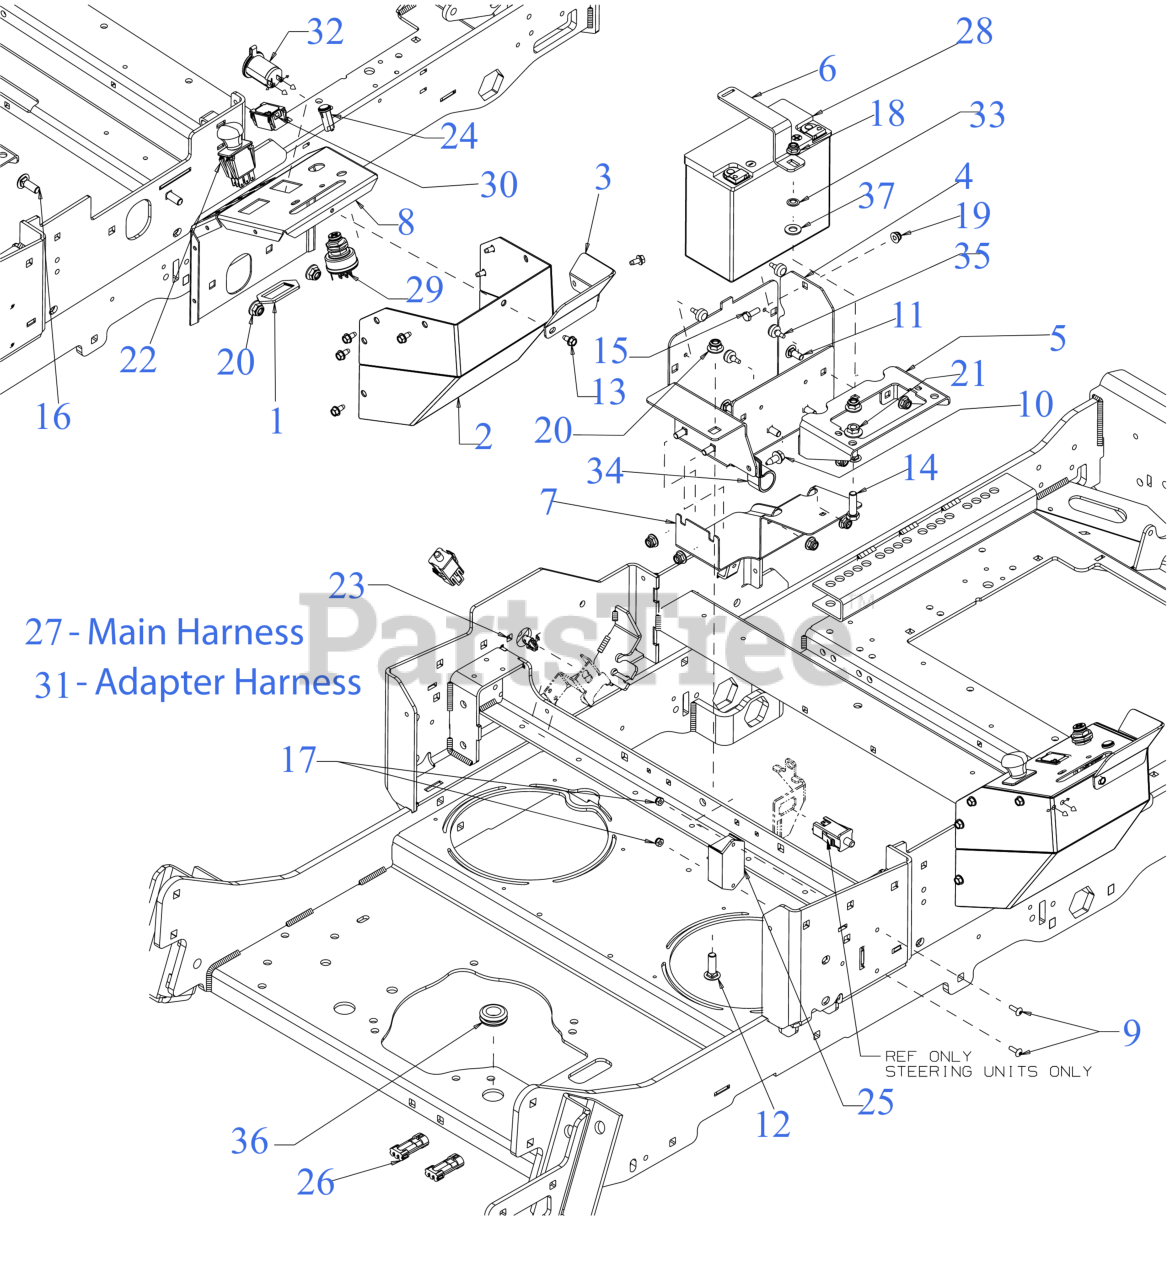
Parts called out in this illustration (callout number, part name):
1	BRACKET-PTO SWITCH
4	BATTERY MOUNT BRACKET
5	FUSE/RELAY MOUNT BRACKET
6	BATTERY SUPPORT BRACKET
7	HOSE/BELT COVER
8	CONTROL POD (RH)
9	SCREW #10-24 x .62
10	SCREW 5/16-18 x .750
11	CARRIAGE BOLT 5/16-18 x .75
12	CARRIAGE BOLT 3/8-16 X1.25 GR5
13	SCREW 1/4-20 X.500
14	SCREW 3/8-16 x 1.25 GR5
15	SCREW 1/4-20X.75 GR5
16	CARRIAGE BOLT 3/8-16 x 1.00 GR5
18	FLANGE LOCK NUT 5/16-18
19	FLANGE LOCK NUT
21	FLANGE LOCK NUT
22	PTO SWITCH (BLACK KNOB) TEXT SYM
23	3 POLE SWITCH ( NC-NO-NO)
24	INDICATOR LIGHT-RED
25	CONTROL PANEL (SOFT CLUTCH)
26	SEALED CAP ASSEMBLY
27	MAIN HARNESS
28	BATTERY (300 CCA)
29	KEY SWITCH
29	PRO-Z KEY SET
30	HOUR METER
31	ADAPTER HARNESS
32	POWER RECEPTICAL
34	HOSE CLAMP 1.0"
35	BUMPER, .62 DIA x .3
36	RUBBER GROMMET
37	FLAT WASHER
